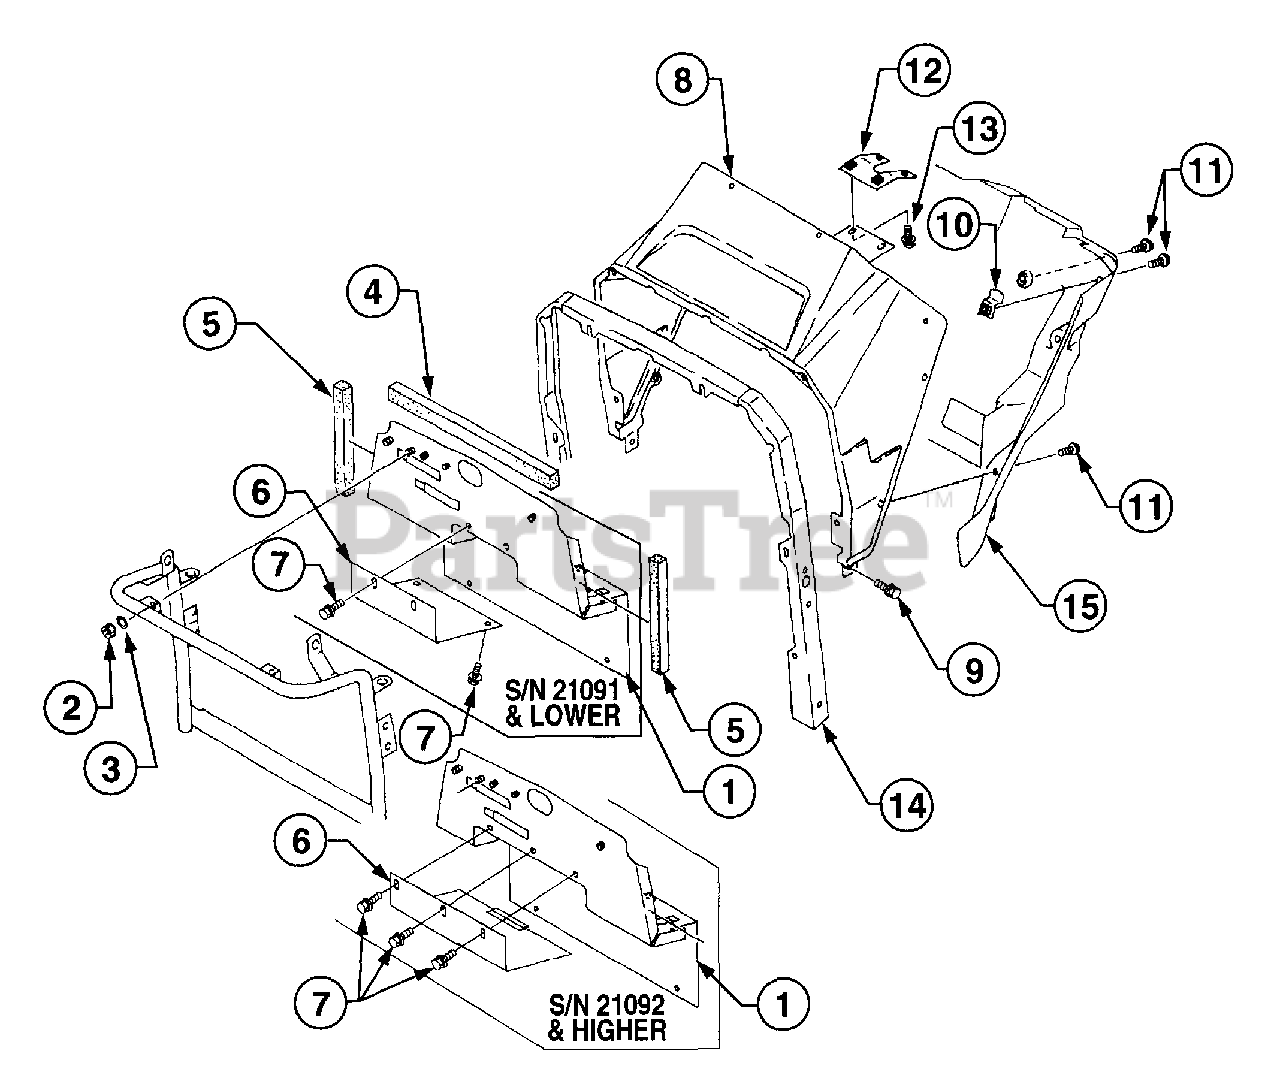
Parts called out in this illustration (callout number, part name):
1	Cover
6	Cover
7	Bolt, w/Washer
9	Bolt, w/Washer
15	Cover, Panel Rear
